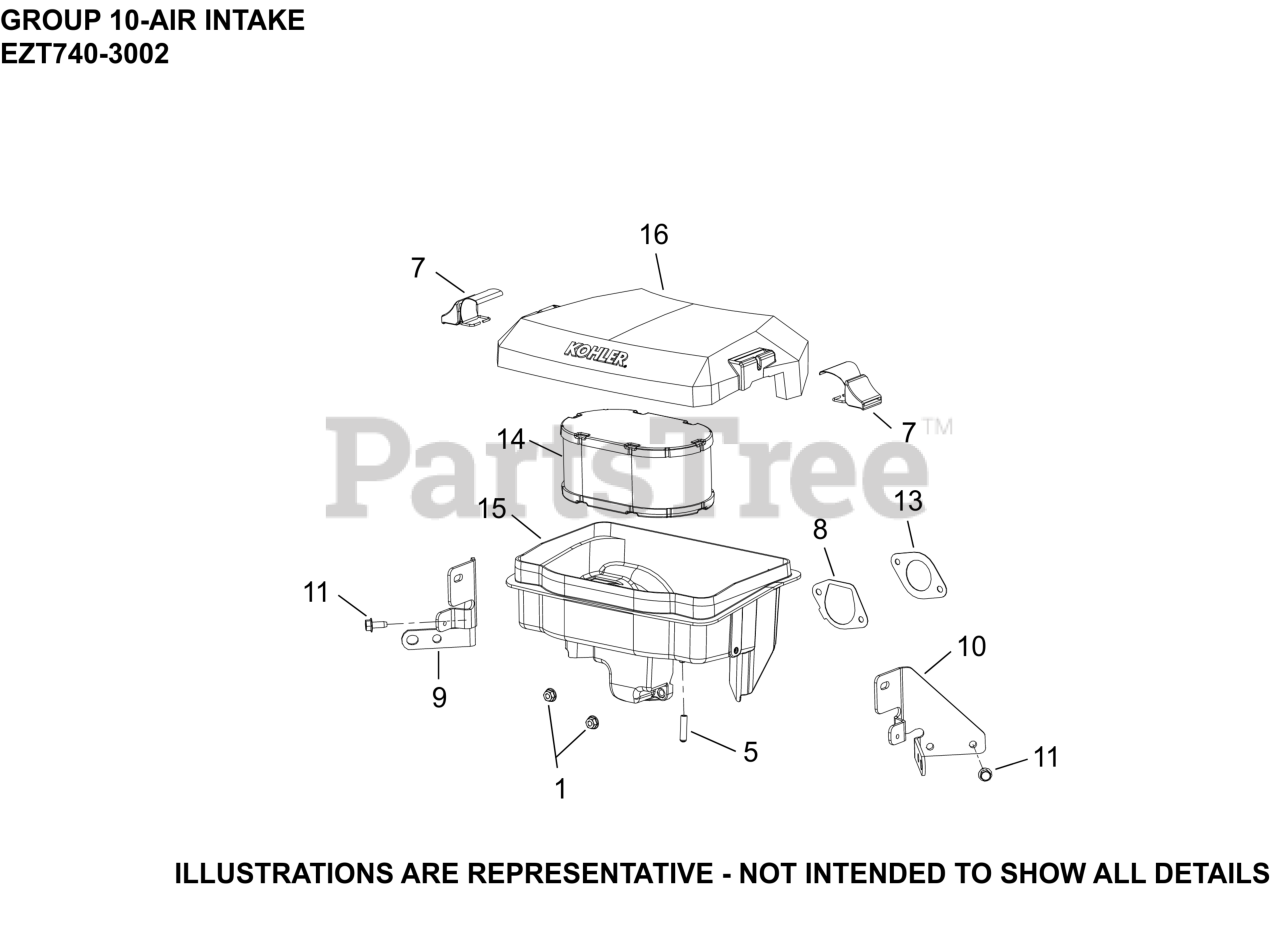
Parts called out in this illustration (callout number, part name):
1	NUT, FLG M6X1.0
5	CAP, MASKING
7	LATCH ASSY, AIR CLEANER COVER
8	GASKET, AIR CLEANER BASE
9	BRACKET, AIR CLEANER BASE (#1 SIDE)
10	BRACKET, AIR CLEANER BASE (#2 SIDE)
11	SCREW, THREAD FORMING
13	GASKET, THROTTLE BODY
14	ELEMENT, AIR FILTER
15	BASE, AIR CLEANER ASSEMBLY (LPAC)
16	COVER, AIR CLEANER (LPAC)
NI	ELEMENT, PRE-CLEANER
NI	SCREW, HI-LOW
